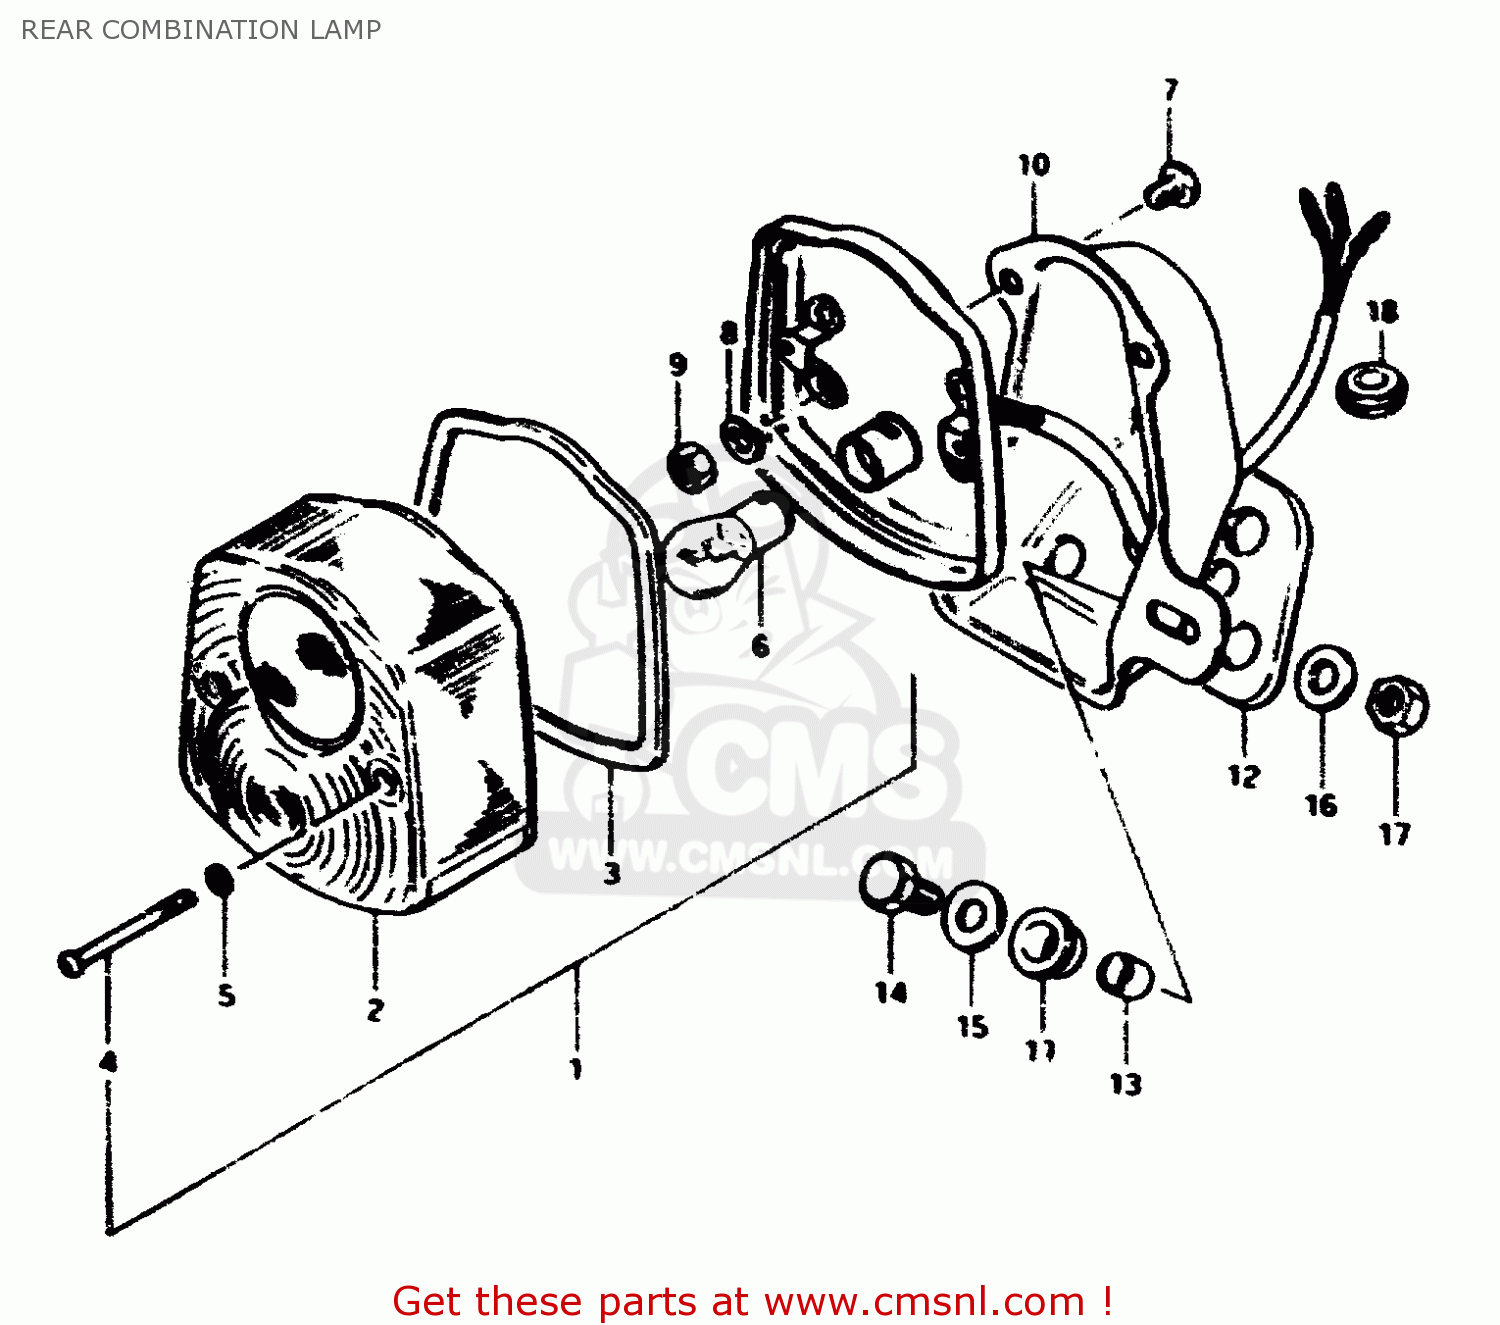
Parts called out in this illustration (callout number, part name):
1	LAMP UNIT, TAIL
2	LENS,RR COMBI
3	GASKET (NAS)
4	SCREW
5	GASKET (NAS)
6	BULB (6V,21/5W)
7	SCREW
8	LOCK WASHER
9	NUT
10	BRACKET UNIT,TAIL LAMP
11	CUSHION
12	CUSHION
13	SPACER
14	BOLT
15	WASHER (6.5X20X1.2)
16	WASHER
17	NUT
18	GROMMET
